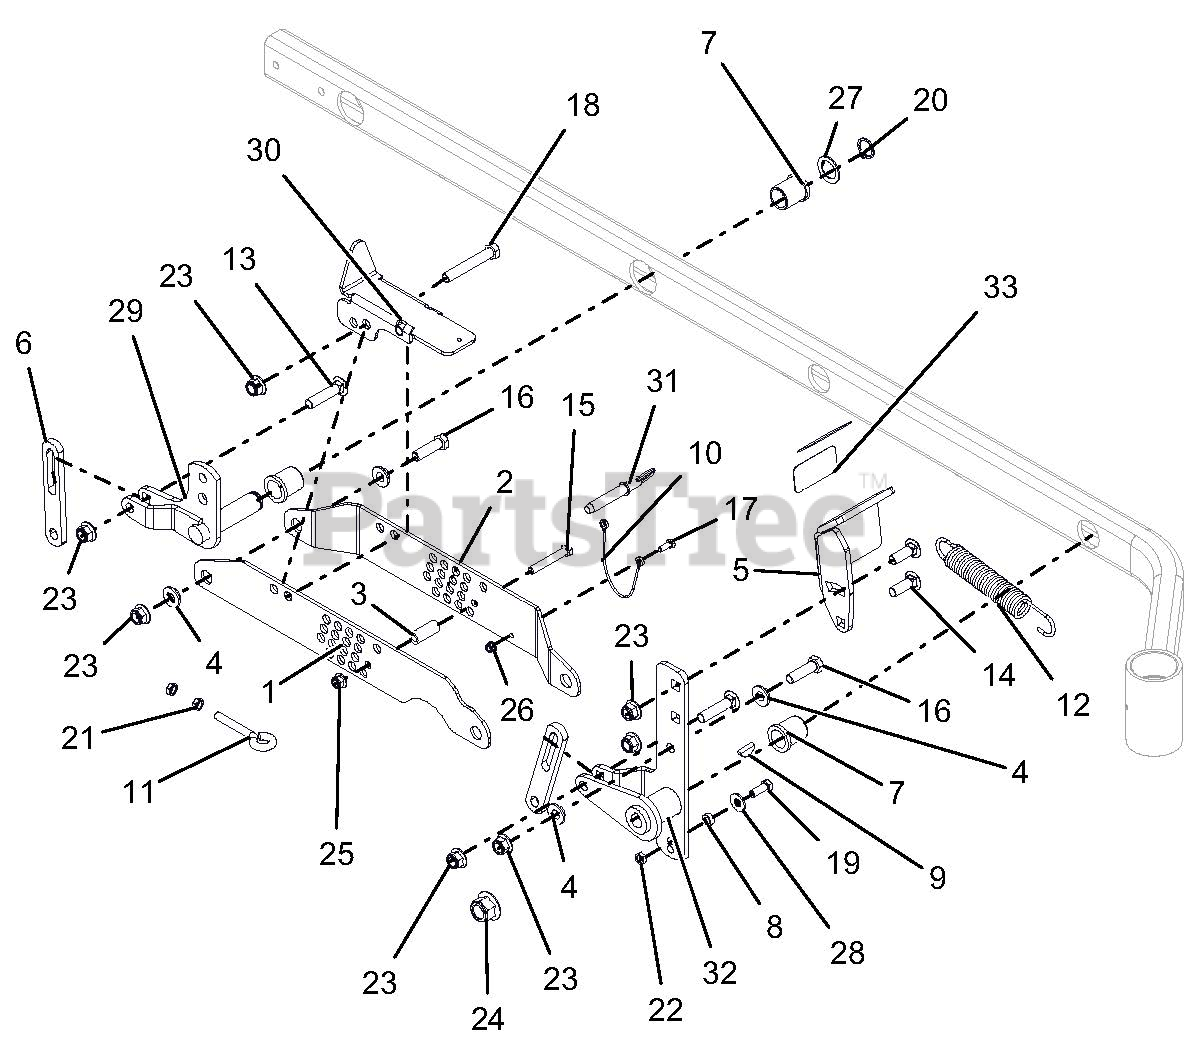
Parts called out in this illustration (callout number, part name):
1	BRKT, RH OUTBOARD LIFT/CUT HEIGHT
2	BRKT, RH INBOARD LIFT/CUT HEIGHT
3	SPACER, .375 X .625 X 1.54
4	BSHG, FLANGE .515X.750X.31X1.12
5	PEDAL, ADJUSTABLE FOOT LIFT
6	LINK, DECK LIFT - LONG
7	BSHG-FLG 1.00X1.25X1.5X1.5
8	BSHG, SLV .377X.624X.235
9	KEY, WDRF .25 X 1.00 HRD #15
10	LANYARD, 12"
11	BOLT, EYE .375-16
12	SPRG, TENSION .162 X 1.250 X 8.250
13	BLT-RDHDSQNK .50-13X2.25 G5 Y
14	BLT-RDHDSQNK .50-13X1.50 G5 YWZC
15	BLT-HEX .38-16X2.50 GR5 YWZC
16	BLT-HEX .50-13X1.75 GR5 YWZC
17	BLT-HEX .25-20X.75 GR5 YWZC
18	BLT-HEX .50-13X3.25 GR5 YWZC
19	BLT-HEX .38-16X1.00 GR5 YWZC
20	RG-RTNG-EXT 1.00X.078
21	NUT, JAM .375-16 YWZC
22	@NUT-LK-CTR-JAM .375-16 YWZC
23	NUT-LK-NYL-FLG .50-13 YWZC
24	NUT-LK-NYL-FLG .75-10 YWZC
25	NUT-LK-NYL-FLG .38-16 YWZC
26	NUT-LK-NYL-FLG .25-20 YWZC
27	WSHR-FL-STL 1.010X1.505X.062 YWZC
28	WSHR-FL-STL.438X1.00X.083 YWZC
29	WLDMT, RH REAR DECK LIFT
30	WLDMT, MECHANICAL LOCK-UP
31	PIN, .50 X 2.00 USABLE LG BALL
32	WLDMT, TAPERED LIFT ARM FRONT LH
33	GRIP, PEDAL 1.50 X 3.00
